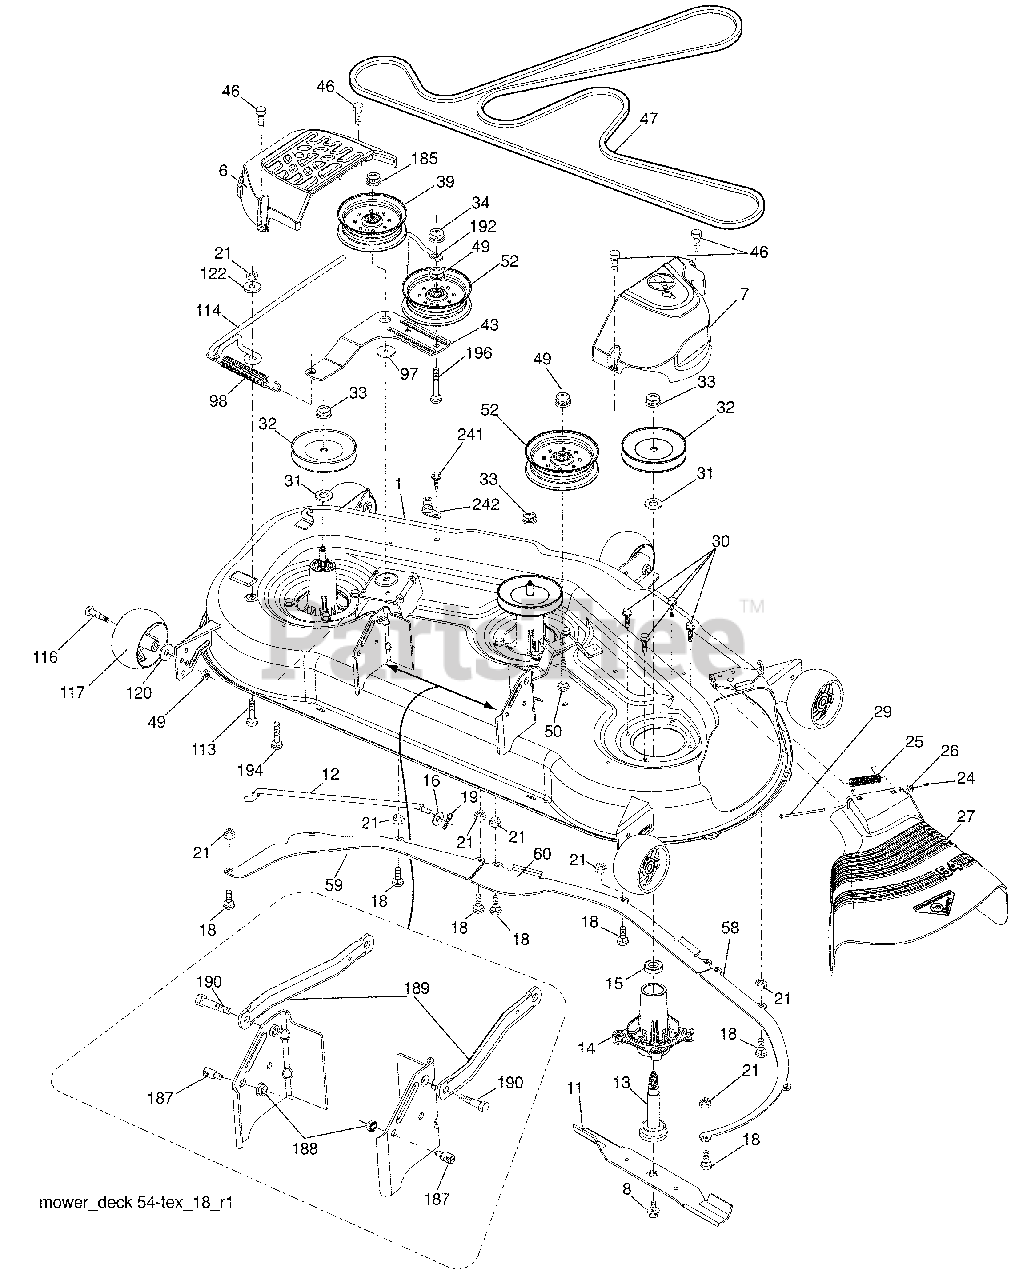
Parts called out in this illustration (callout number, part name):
1	Deck, Complete, 54"
1	Deck, Shell only, 54"
6	Cover Mandrel LH
7	Cover Mandrel RH
8	Bolt 7/16 Asm. Blade
11	Blade Bagging
11	Blade Mulching
12	Rod Anti-Sway
13	Shaft Asm. w/Lower Bearing
14	Housing, Mandrel
15	Bearing, Ball, Mandrel
16	Washer 3/8
18	Bolt Carriage 5/16-18 x 5/8
19	Pin Cotter 5/16 Bowtie
21	Nut, Crownlock 5/16-18 unc
24	Cap Sleeve
25	Spring, Torsion
26	Nut, Push
27	Deflector Shield
29	Rod, Hinge
30	Screw, Thdroll Washer Head
31	Washer, Spacer Mower Vented
32	Pulley, Mandrel
33	Nut, Flg. Top Lock
34	Nut Crownlock 3/8-16 unc
39	Pulley, Idler, 4.50
43	Arm, Idler
46	Screw, Thdroll. 1/4-20 x 5/8
47	Belt Deck Drive
49	Nut, Lock Flg. 3/8-16 unc
50	Bolt Rdhd Sqnk 3/8-16 unc x 2
52	Pulley Idler
58	Baffle Right
59	Baffle Left
60	Baffle Center
97	Washer Hardened
98	Spring Drive
113	Bolt Rdhd Sqnk 5/16-18 x 3/4
114	Rod Tension Relief
116	Bolt, Shoulder
117	Gauge Wheel
120	Washer 13/32 x 1-1/4 x 12 Ga.
122	Bushing Tension Relief
184	Nut Lock Hex Flange
185	Nut Lock Flange 7/16-14 Gr. 5
187	Stud Fastener w/"D" Anti-Rotation
189	Arm Susp. Mower Rear
190	Bolt Shoulder
192	Keeper Belt Idler
194	Bolt Carr Sqnk 7/16-24 x 2
196	Bolt Rdhd 3/8-16 x 2-1/2 Gr. 5
241	Screw #10-32.5 3/8 Flange
242	Port Washout
